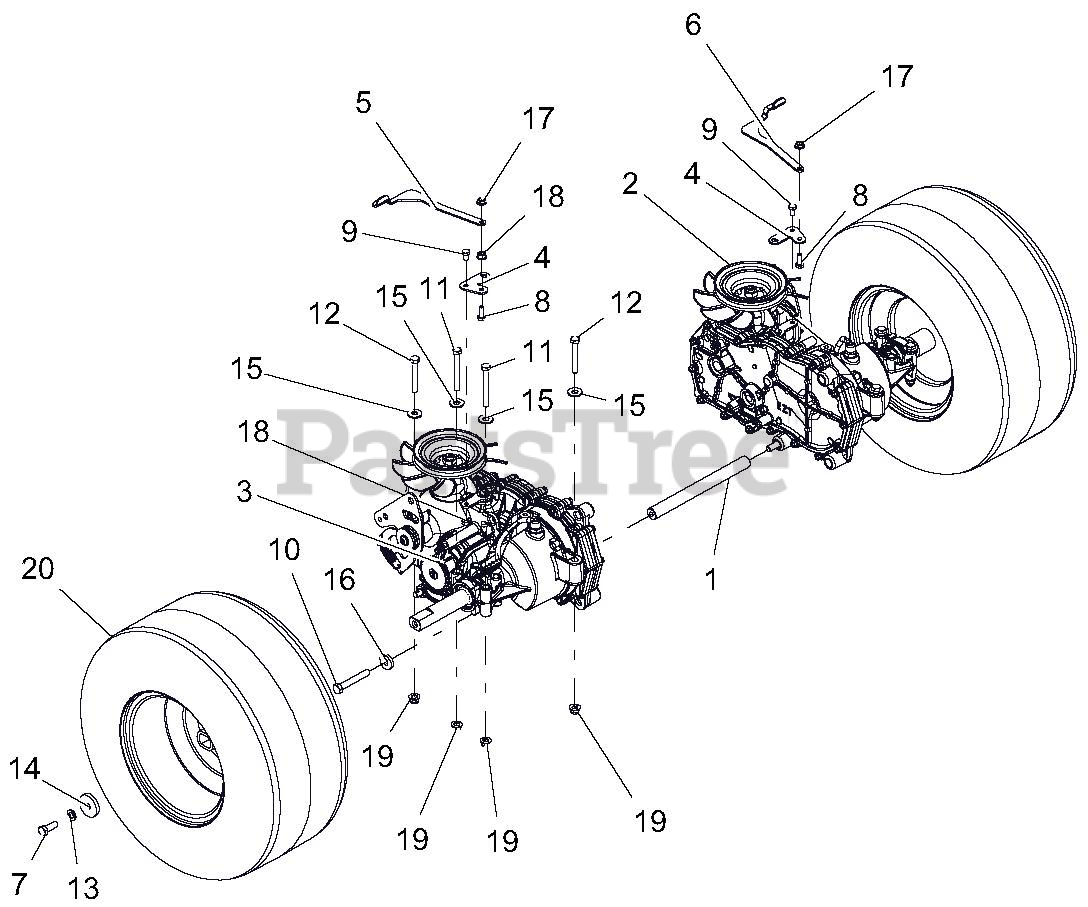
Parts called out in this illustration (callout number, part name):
1	ROD, TRANSAXLE BRACE
2	TRANSAXLE, LH EZT D-SHAFT SHORT
3	TRANSAXLE, RH EZT D-SHAFT SHORT
4	BRKT, DUMP VALVE EXTENSION
5	BRKT, VALVE DUMP RH
6	BRKT, VALVE DUMP LH
7	BLT-HEX .38-16X1.00 GR5 YWZC EP30
8	BLT-HEX .25-20X.75 GR5 YWZC
9	BLT-HEX .25-20X.50 GR5 YWZC
10	BLT-HEX .38-16X2.50 GR5 YWZC
11	BLT-HEX .31-18X2.75 GR5 YWZC
12	BLT-HEX .31-18X2.25 GR5 YWZC
13	WSHR-LK .38X.094 REG YWZC
14	WSHR-FL-STL .406X1.50X.245 YWZC
15	WSHR-FL-STL.38X.875X.083 YWZC
16	WSHR-FL-STL .406X1.00X.188 YWZC
17	@NUT-SPNLK-FLG .25-20 YWZC
18	NUT, LK-TOP-FLG .25-20 YWZC
19	NUT-LK-NYL-FLG .31-18 YWZC
20	WHEEL, 18X8.5-8 4P DD HUB
